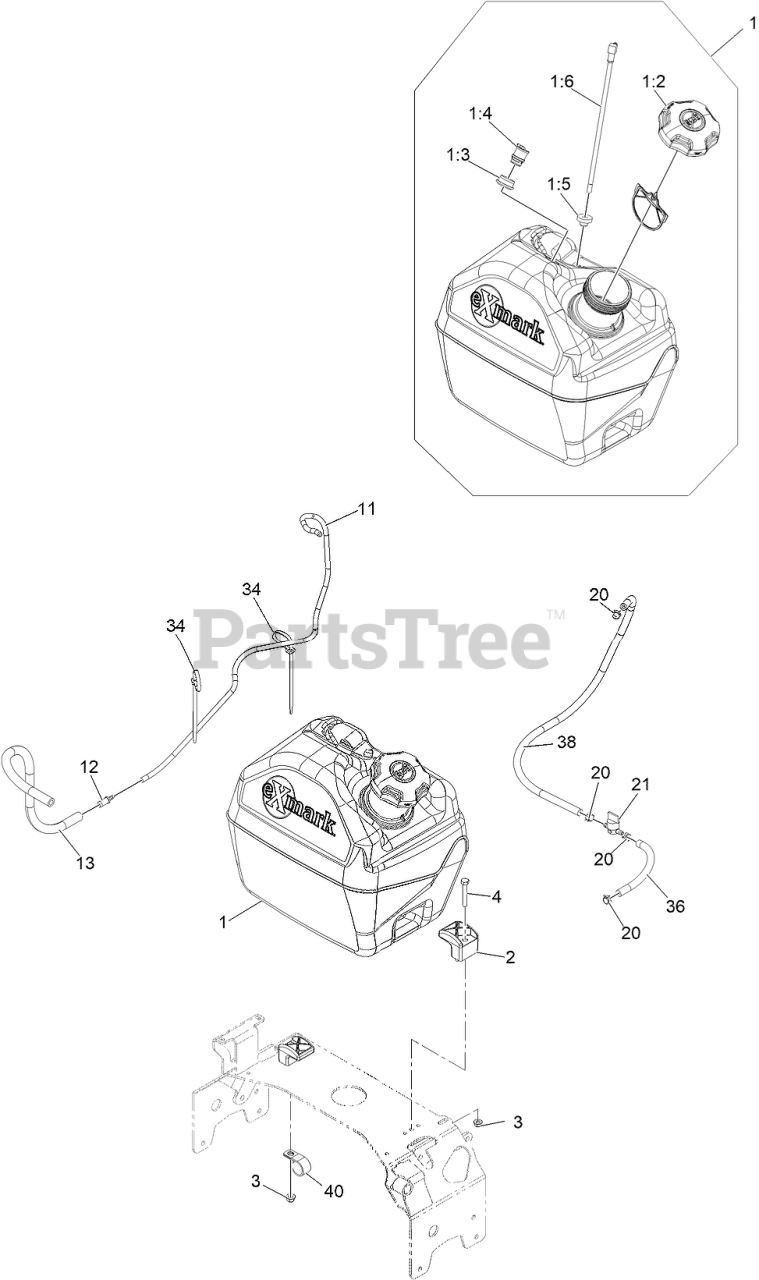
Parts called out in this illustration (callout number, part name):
1	Fuel Tank ASM, 5 Gal
1:2	CAP-FUEL, RATCHETING
1:3	GROMMET
1:4	VALVE-VENT, FUEL
1:5	BUSHING
1:6	FITTING, FUEL W/LINE AND SCREEN
3	NUT-HF, NI
4	SCREW-HH
11	HOSE, EMISSIONS
12	FITTING-STRAIGHT
13	HOSE-FUEL
20	CLAMP-HOSE
21	VALVE-FUEL
34	TIE-CABLE
36	HOSE-FUEL
38	HOSE-FUEL
40	CLIP-LOOM
